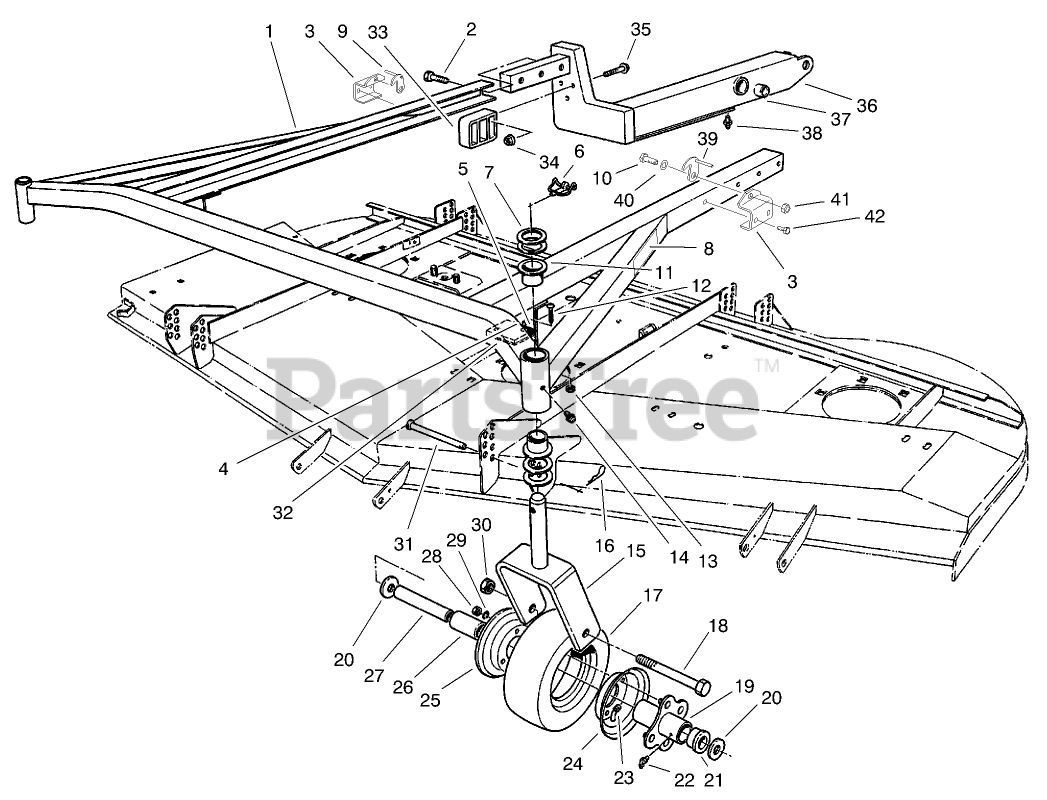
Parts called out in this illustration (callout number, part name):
1	CARRIER FRAME
2	SCREW-HH
3	Bracket-Latch(Europe)
4	SPACER
5	CUSHION-RUBBER
6	PIN-LYNCH
7	WASHER-THRUST
8	DECAL-HOC, LH
8	DECAL-HOC
9	Retainer-Deck RH(Europe)
10	SCREW-HH
11	BUSHING
13	NUT-LOCK, NI
14	FITTING-GREASE
15	Castor Fork
16	PIN-HAIR
18	SCREW-HH
19	HUB-CENTER
20	WASHER-FLAT
21	BEARING-OUTSIDE
22	FITTING-GREASE
23	TUBE-INNER (W/VALVE)
24	FEMALE WHEEL HALF
25	MALE WHEEL HALF
26	BEARING-ROLLER
27	SPANNER-TIRE
28	NUT-HEX
29	WASHER-LOCK
30	NUT-HEX
31	PIN-CLEVIS
32	SHIM-CUSHION
33	Cradle-Rear
34	NUT-FLANGE
35	SCREW-HHF
36	Assembly-Lift Arm, R.H. (Incl. Ref. #37-38)
37	BUSHING
38	FITTING-GREASE
39	Retainer-Deck LH(Europe)
40	WASHER-SPRING
41	NUT-LOCK, NI
42	SCREW-HWHTF
